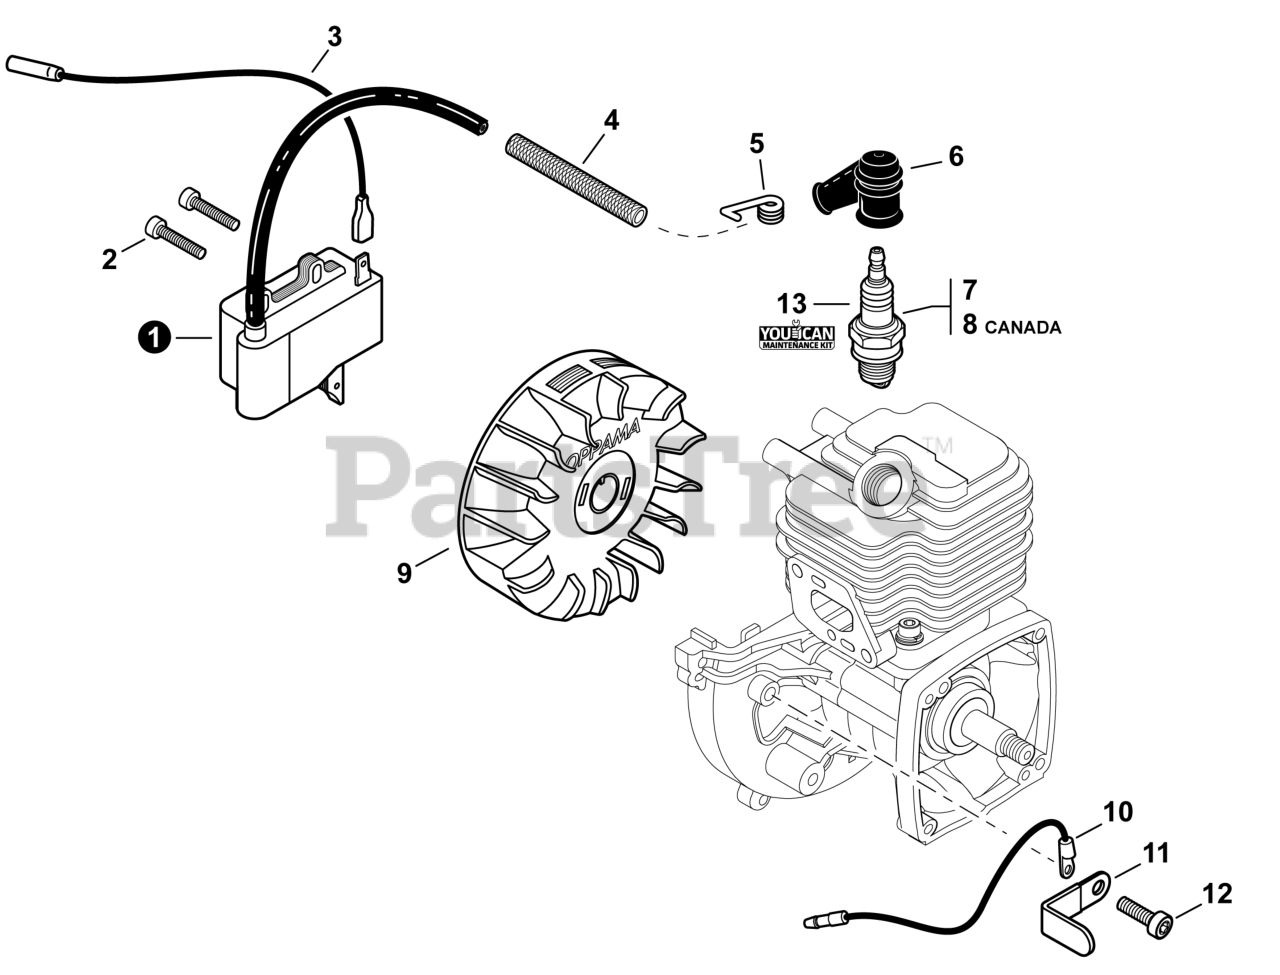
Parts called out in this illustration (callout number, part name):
1	COIL, IGNITION
2	BOLT, TORX 4×20
3	LEAD - IGNITION L= 210
4	TUBE, INSULATOR Ø8 L= 65
5	TERMINAL, SPARK PLUG
6	CAP, SPARK PLUG
7	SPARK PLUG - BPM8Y
8	SPARK PLUG - BPMR8Y
9	FLYWHEEL
10	LEAD - GROUND
12	BOLT, TORX 5×10
13	TUNE-UP KIT - YOUCANT
